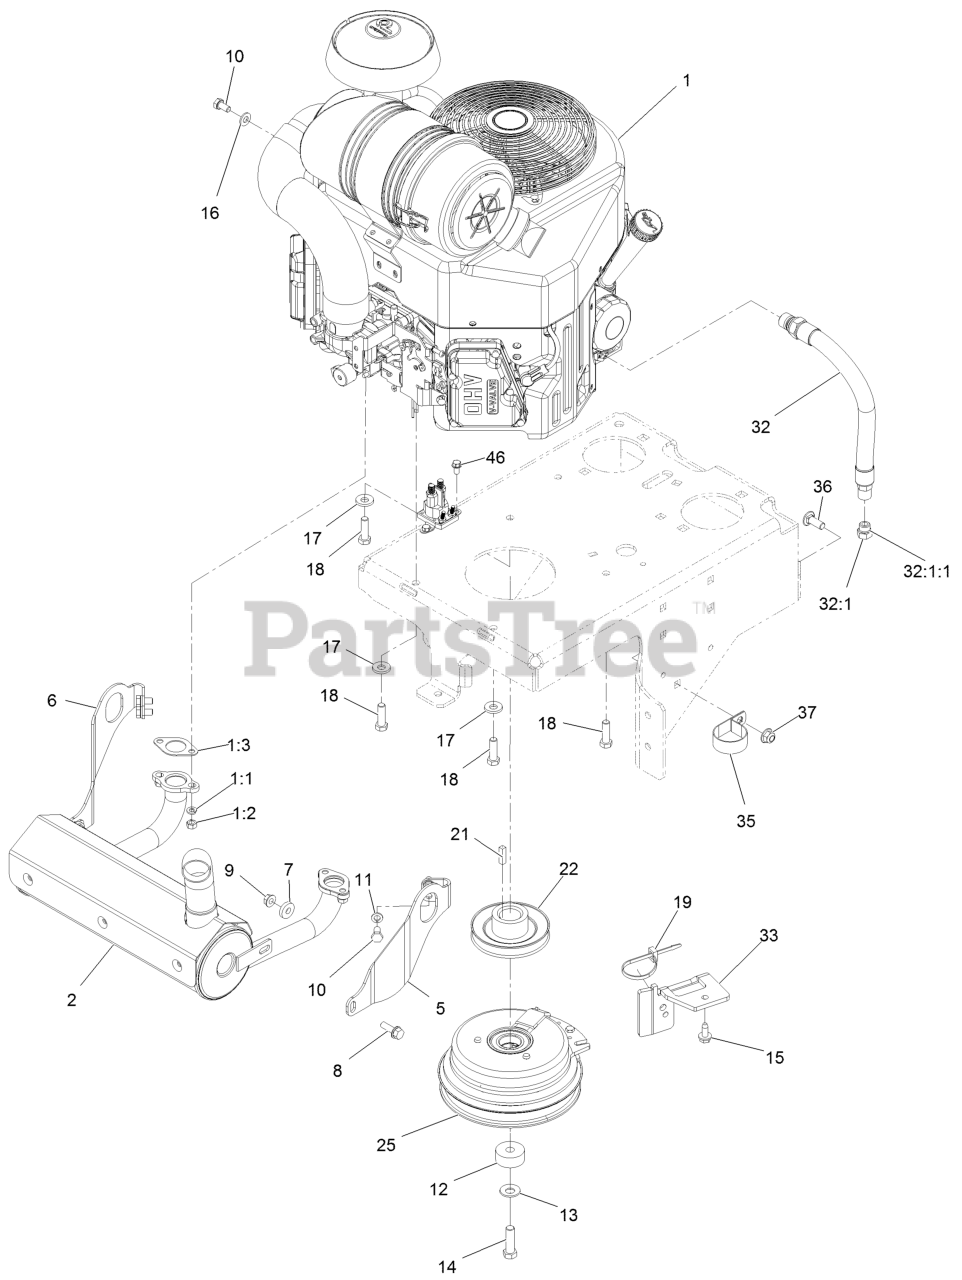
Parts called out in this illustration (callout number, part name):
1	Engine Kawasaki
1:1	WASHER-LOCK
1:3	GASKET-EXHAUST
2	MUFFLER, KAWASAKI, 22-26
5	BRACKET-MUFFLER MOUNT, LH
6	BRACKET-MUFFLER MOUNT, RH
8	SCREW-HHF
10	SCREW-HH
11	WASHER-LOCK
12	KEEPER-CLUTCH
13	WASHER-SPRING
14	SCREW-HH
15	Screw-HWH 5/16-18 X 3/4 Tf
16	WASHER-PLAIN
17	WASHER-BELLEVILLE
18	SCREW-HH
19	TIE-CABLE
25	CLUTCH-200 FT-LB, 1.125 B
32	ENGINE OIL DRAIN HOSE ASM
32:1	PLUG-HH
32:1:1	O-RING
33	BRACKET-ANCHOR, CLUTCH
35	CLAMP-R
36	SCREW-CARR
37	NUT-HF, NI
46	SCREW-HWH
